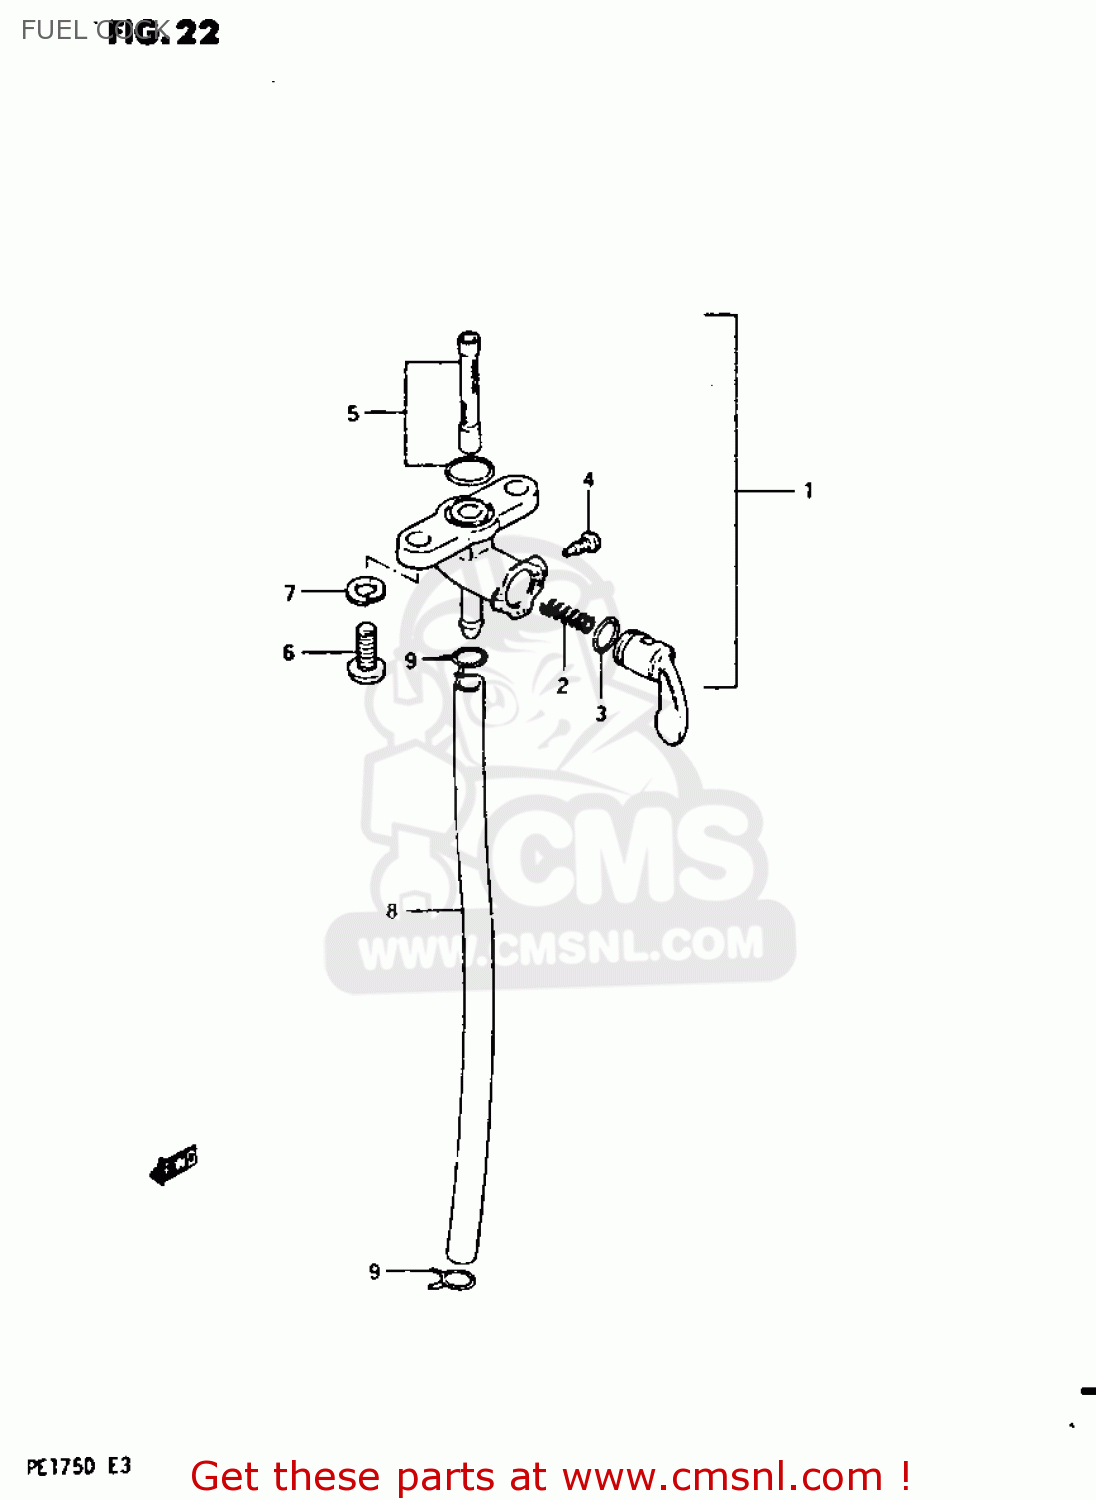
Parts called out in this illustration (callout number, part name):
1	COCK ASSY,FUEL
2	SPRING,FUEL COCK VALUE
3	O RING,LEVER
4	SCREW
5	FILTER SET FUEL
6	SCREW
7	WASHER,LOCK
8	HOSE
9	CLIP
